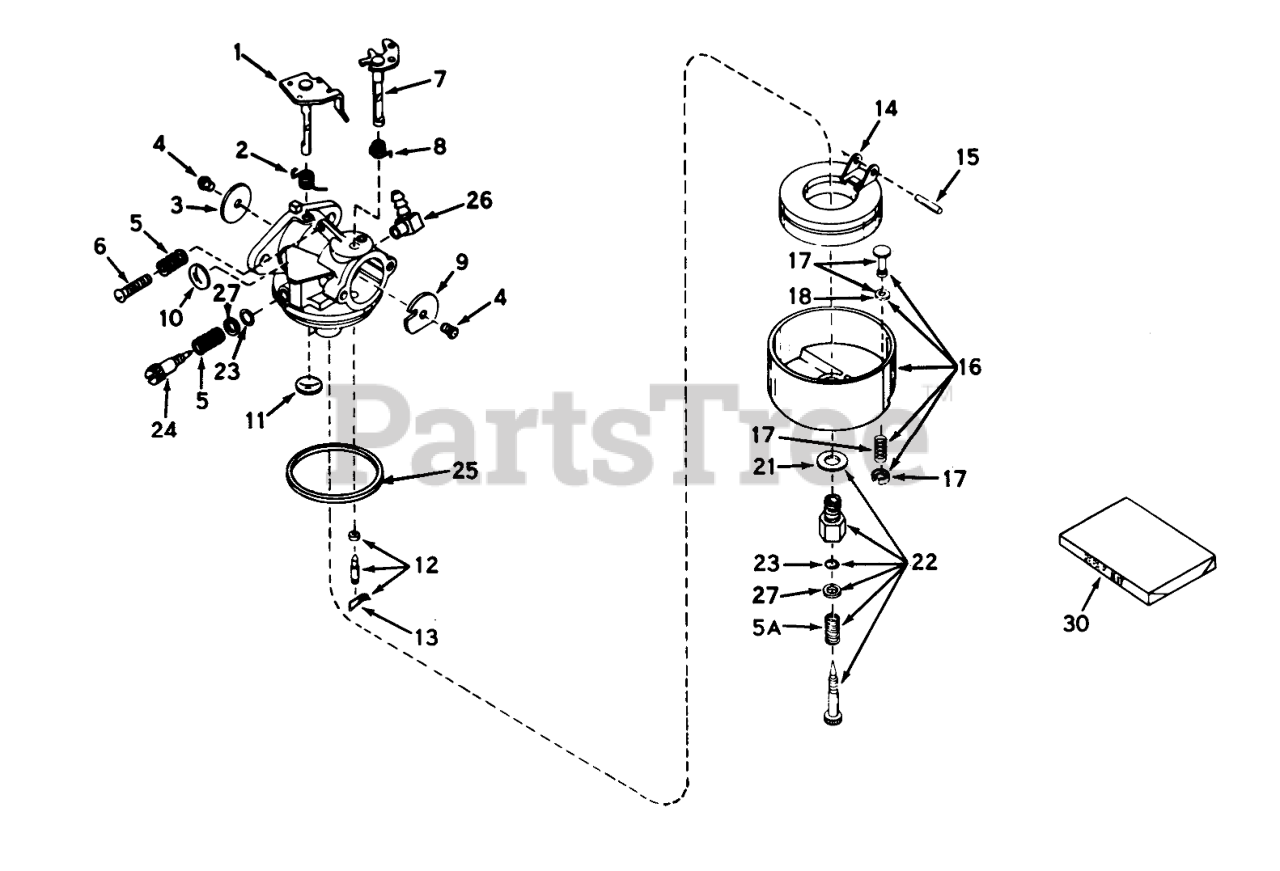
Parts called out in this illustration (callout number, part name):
1	Throttle Shaft and Lever ASM
2	Spring, Throtte Return
3	Shutter-Throttle
4	Screw-Shutter
5	Spring-Tension
6	Screw-Throttle Crack Screw / Idle Speed
7	Shaft& Lever Assy., Choke
8	Spring, Choke return
9	Shutter, Choke
10	Plug-Welch, Idle Mixture Well
11	Plug-Welch, Atmospheric Vent
12	Inlet Needle, Seat & Clip Assy. (Incl . No. 13)
13	Clip-Spring
14	Float,Carburetor
15	Shaft-Float
16	Bowl & Drain Assy., Float (Incl. No. 17)
17	Plunger Assy., Drain (Incl. No. 18)
18	Gasket-Plunger, Drain
21	Washer-Bowl Nut
22	Adjustment Screw Assy., Main (Incl. Nos. 5A, 21, 23 & 27)
23	"O"Ring
24	Screw, Idle Adj.
25	O Ring-Bowl, Float
26	Fitting, Fuel Inlet
30	Repair Kit
